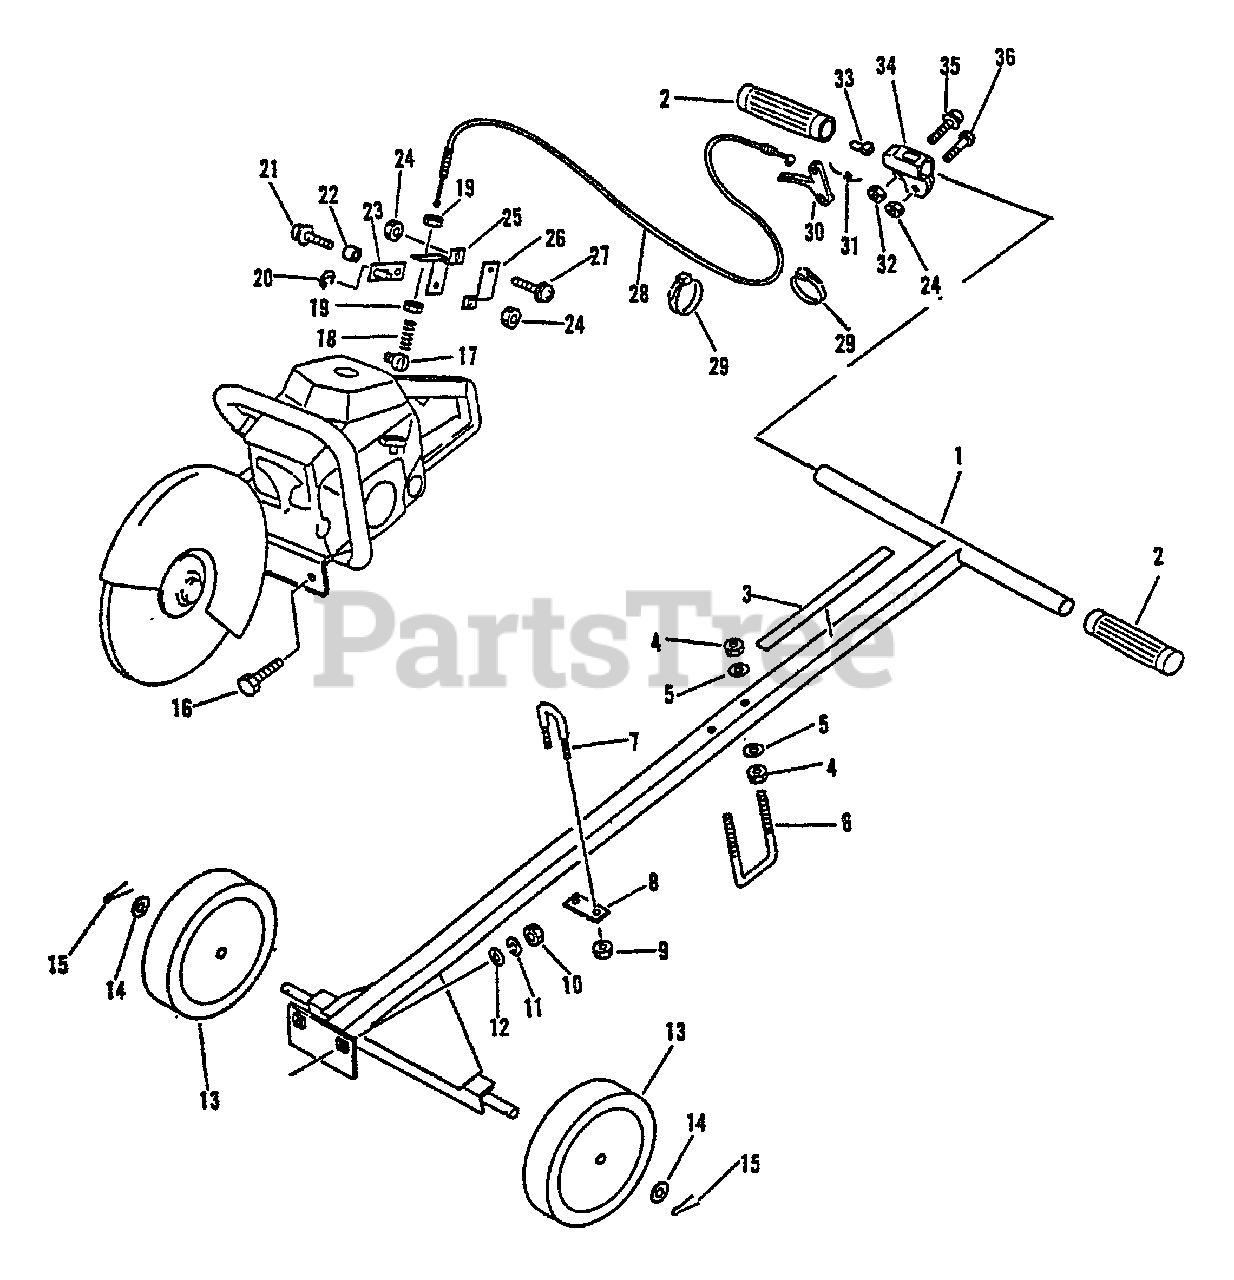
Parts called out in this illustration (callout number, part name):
1	CART
2	GRIP
3	LABEL - CAUTION
6	U-BOLT
8	PLATE
9	NUT - 1/4-20
10	NUT - 5/16-18
13	WHEEL
15	PIN, COTTER 2×22
18	SPRING, TRIGGER
20	E-RING 4
21	SCREW 5×22
22	SPACER 6.2×7.8×6
23	TRIGGER, THROTTLE
24	NUT, LOCK M5
25	BRACKET
26	TRIGGER, MOUNTING BRACKET
27	SCREW 5×16
28	CABLE, THROTTLE
29	TIE, CABLE
30	TRIGGER, THROTTLE
31	SPRING, THROTTLE
32	NUT M5
33	GUIDE, CABLE
34	BRACKET, TRIGGER
35	SCREW 5×35
